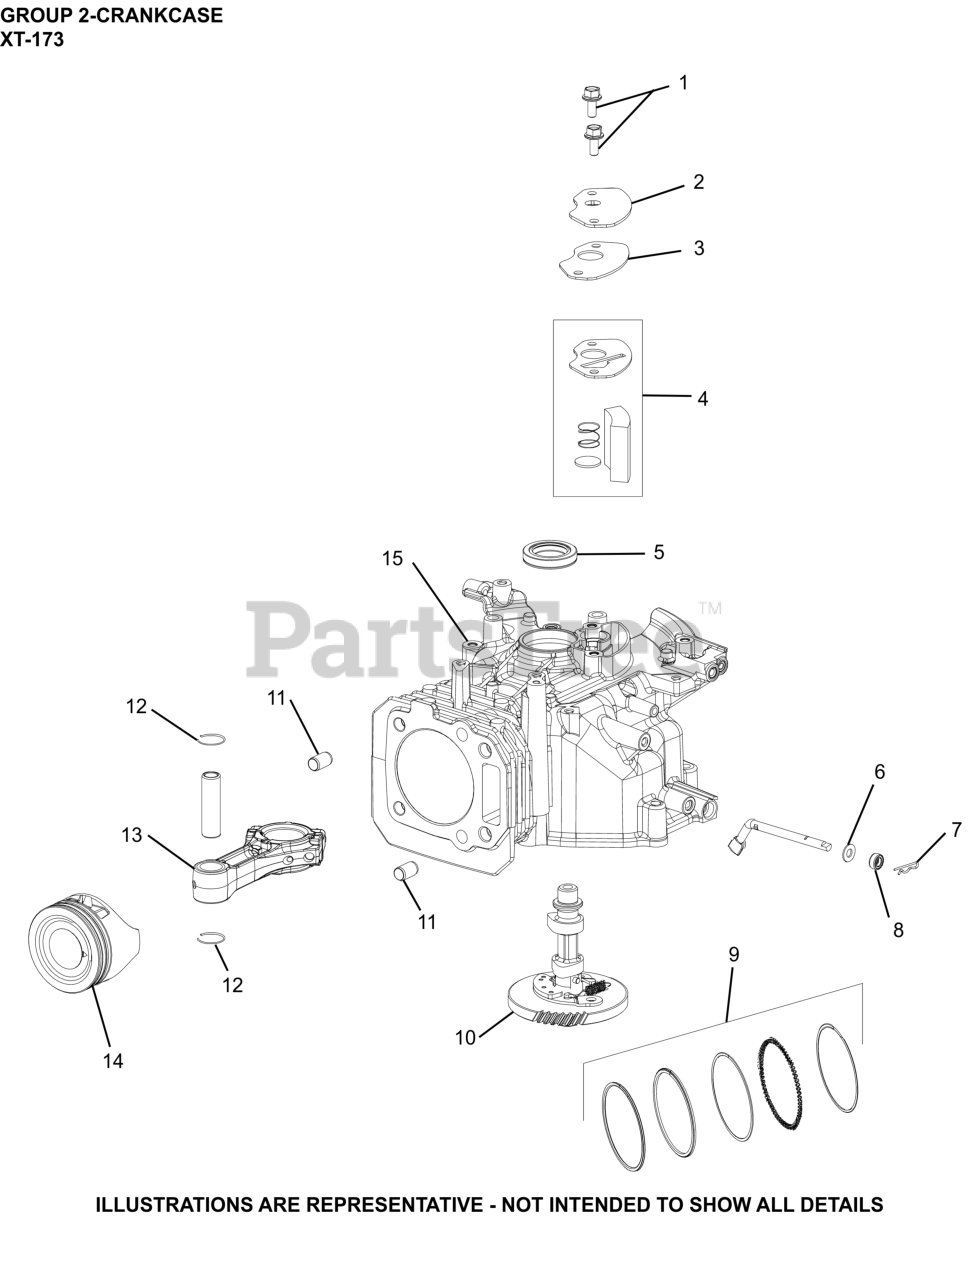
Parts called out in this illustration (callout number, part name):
1	SCREW, HEX FLANGE (M6)-USE 25 086 433-S
2	COVER, BREATHER - (#14096125S)
4	KIT, BREATHER FILTER
5	SEAL, CCASE/FLYWHEEL
6	WASHER, FLAT (DIA 13MM O.D.)-(#1446830S)
7	CLIP, GOVERNOR SHAFT
8	SEAL, OIL
10	CAMSHAFT ASSEMBLY-(#1401013S)
12	RETAINER, PISTON PIN
13	CONNECTING ROD
15	CRANKCASE- (#DSC)
NI	SHAFT, GOVERNOR CROSS
NI	PIN, PISTON
NI	PIN, DOWEL (8MM)-(#DSC)
NI	KIT, PISTON
NI	SCREW, HEX FLANGE (M7)
